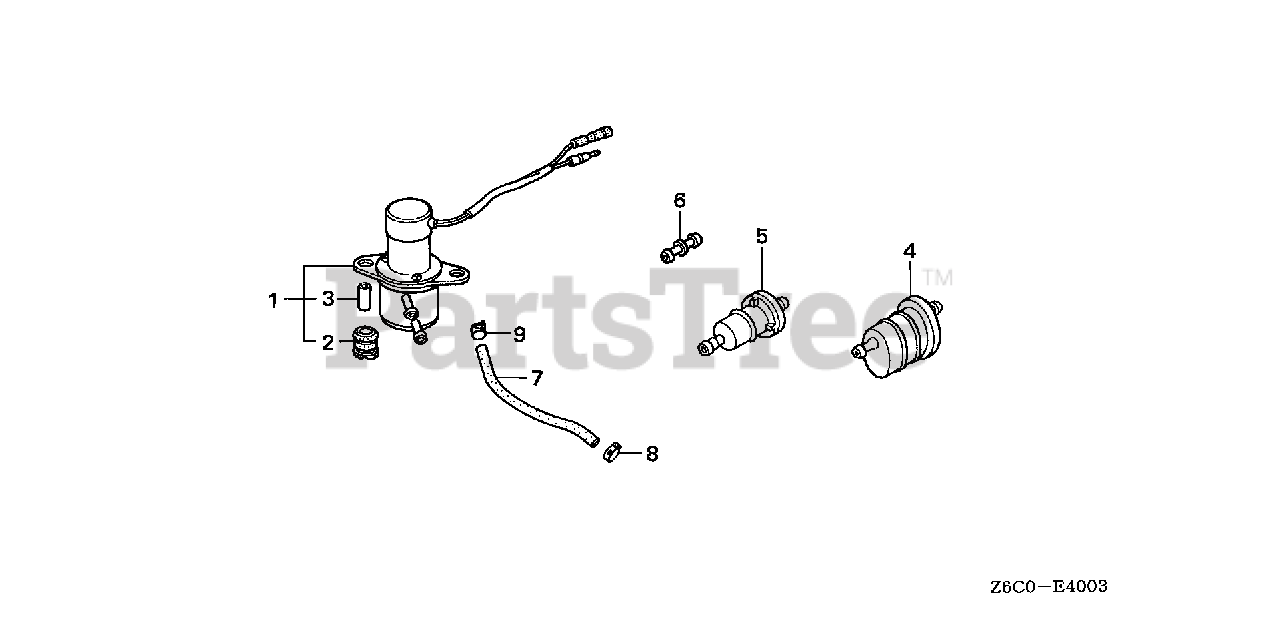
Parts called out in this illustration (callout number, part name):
1	PUMP ASSY., FUEL (MSDS)
2	RUBBER, FUEL PUMP MOUNTING
3	COLLAR, FUEL PUMP DISTANCE
5	STRAINER, FUEL
6	JOINT, FUEL TUBE
7	TUBE, FUEL SPECIAL (FKM)
7	TUBE, FUEL SPECIAL
8	CLAMP, TUBE (D8)
9	CLAMP, TUBE (D8.5)
